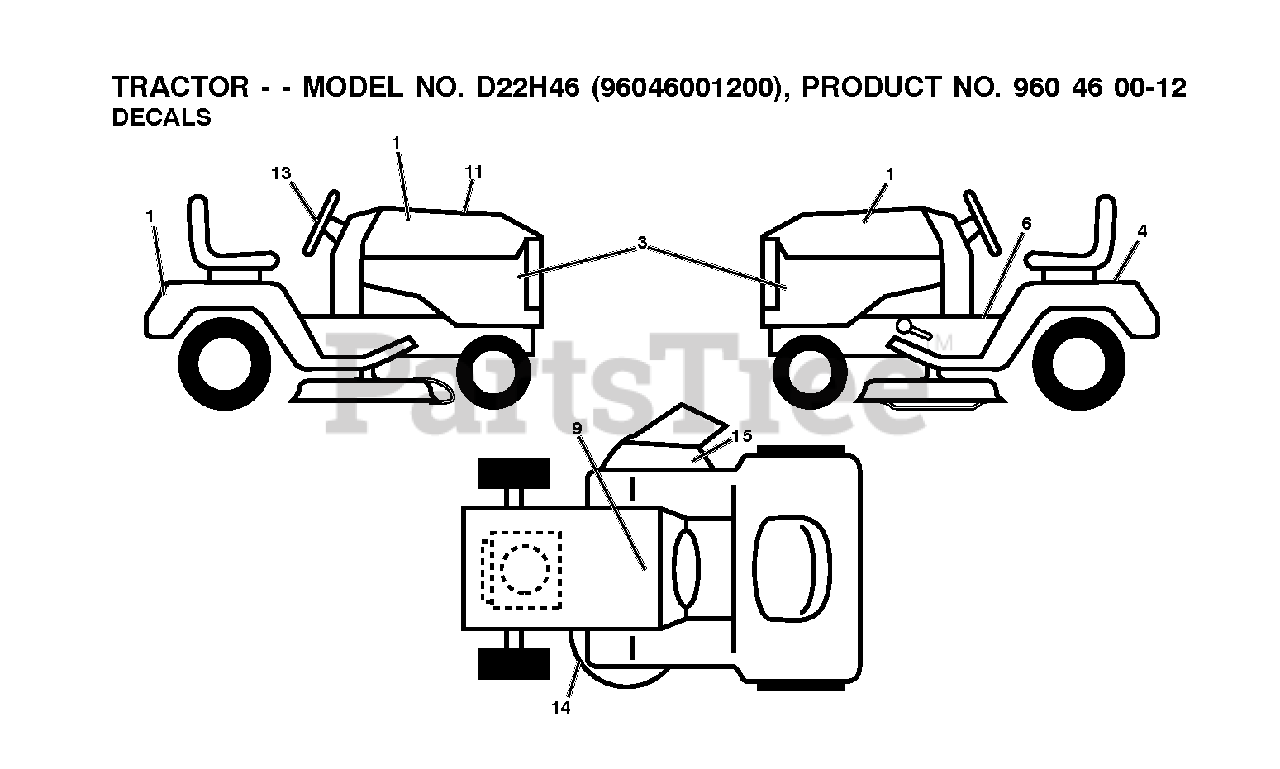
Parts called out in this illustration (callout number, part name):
1	DECAL, DIXON LOGO, DOMED
3	DECAL.PNL.SD.22/46.KOHL.DIXON
4	DECAL SERVICE
6	DECAL.WARN.START.INSTRUCTIONS
9	DECAL BTRY SYMBOLS
11	DECAL.RPL.KHSV715.TLW.46.K46
13	DECAL.WHEEL.STEER.DIXON
14	DECAL V BELT SCHEMATIC
15	DECAL.WARN.KEEP.HAND.AWAY
